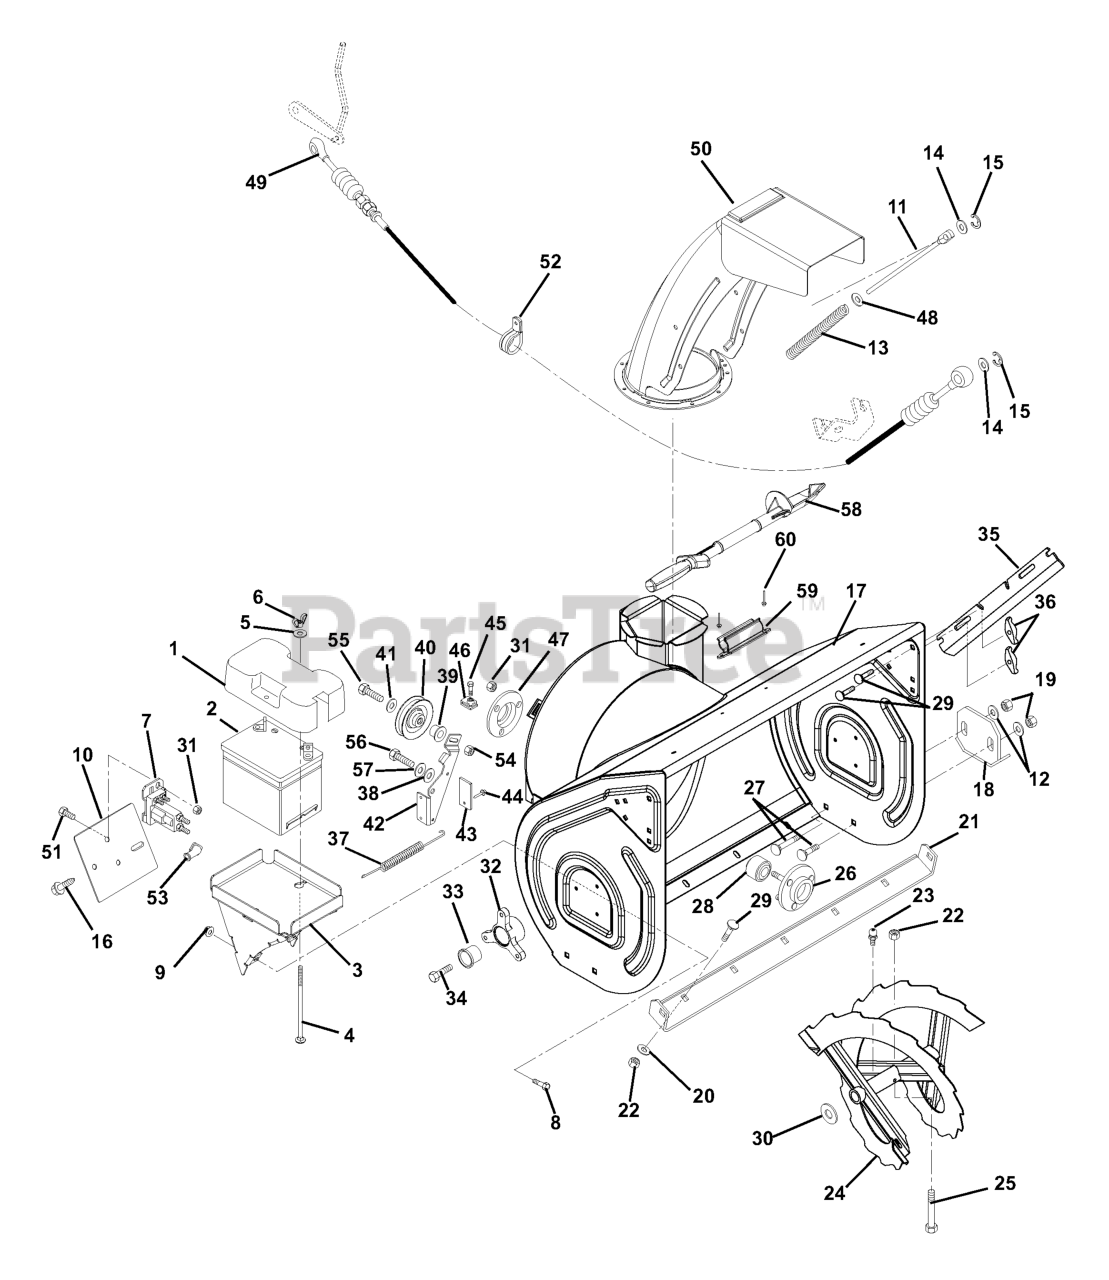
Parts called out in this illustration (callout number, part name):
1	COVER, BATTERY
3	TRAY, BATTERY
4	@BLT-RDHDSQNK .25-20X7.00 G2YZ
5	@WSHR-FL-STL.281X.62X.065 YWZC
6	NUT-LK WING .250-20 YWZC
7	SOLENOID
8	@BLT-HEX .25-20X.75 GR5 YWZC
9	@NUT-SPNLK-FLG .25-20 YWZC
10	COVER, SOLENOID
11	ROD, CHUTE
12	@WSHR-FL-STL.438X1.00X.083 YWZ
13	SPRING, COMP. .08 X .40 X 7.15
14	@WSHR-FL-STL.281X.62X.065 YWZC
15	RG-RTNG-EXT .218X.035 TYPE E
16	@SCR-TAP .25-20X.50 HWH TR YWZ
17	HOUSING, BLOWER-26" W/DECAL
17	HOUSING, BLOWER-28" W/DECAL
17	HOUSING, BLOWER-32" W/DECAL
17	HOUSIG, BLOWER-36" W/DECAL
18	RUNNER, SKID SHOE-1/2" FLANGE
18	SKID SHOE, REVERSIBLE - ORANGE
19	@NUT-LK-CTR .38-16 YWZC
20	@WSHR-FL-STL.38X.875X.083 YWZC
21	BLADE, SCRAPER-26"
21	BLADE, SCRAPER-28"
21	BLADE, SCRAPER-32"
21	BLADE, SCRAPER-36"
22	@NUT-LK-CTR .31-18 YWZC
23	FTG-LUBE .25-28X.256 YWZC
24	RAKE, LH-26"(1 ID X 15.75 OD)
24	RAKE, RH-26" (1 ID X 15.75 OD)
24	RAKE, LH-28" (1 ID X 15.75 OD)
24	RAKE, RH-28" (1 ID X 15.75 OD)
24	RAKE, LH-32" (1 ID X 15.75 OD)
24	RAKE, RH-32" (1 ID X 15.75 OD)
24	RAKE, LH-36" (1ID X 15.75 OD)
24	RAKE, RH-36" (1 ID X 15.75 OD)
25	SHEAR BOLT SERVICE ASSEMBLY
26	BEARING FLANGE
27	@BLT-RDHDSHSQNK.38-16X1.0 G5YZ
28	BRG-BALL .876 X 1.750 X .50
29	@BLT-RHDSSQNK .31-18X.75 G5YZ
30	WSHR-FL-STL 1.010X1.505X.062YZ
31	@NUT-LK-CTR .25-20 YWZC
32	BUSHING, RAKE SHAFT 1"
33	BSHG-FLG, SPLIT NYLINER 1.0"ID
34	@SCR-TAP .25-20X.50 HWH TR YWZ
35	CUTTER, DRIFT
36	KNOB - WING .312-18 UNC
37	SG-TENS .06X.492X5.25 WLD 11
38	WSHR-FL-STL .328X1.0X.094 YWZC
39	SPCR, BRG .315X.50X.688X.281
40	IDLER
41	@WSHR-FL-STL.38X.875X.083 YWZC
42	ARM, AUGER/BRAKE-HIGH W/LINING
43	BRAKE LINING
44	RVT-TBLR .187X.437 RH ST PL
45	BLT-SERHFWH .38-16X.75 YWZC
46	NUT-RETNR .38-16 TINRMAN
47	BEARING FLANGE
48	@WSHR-FL-STL.344X.688X.065YWZC
49	CABLE, DEFLECTOR CONTROL
50	CHUTE, DISCHARGE-W/REMOTE
50	CHUTE, DISCHARGE-ELECTRIC
51	@BLT-HEX .25-20X.50 GR5 YWZC
52	CLAMP, CUSHIONED STEEL
53	BOOT, EYELET TERMINAL
54	@NUT-LK-TOP-FLG .31-18 YWZC
55	@BLT-HEX .31-18X1.25 GR5 YWZC
56	@BLT-HEX .31-18X.75 GR5 YWZC
57	WSHR-LK .312X.097 HVY YWZC
58	DEVICE, SNOW CLEAN OUT
59	MOUNT, SNOW CLEAN OUT
60	RVT-POP .187X.45 DOME SS FBF64
